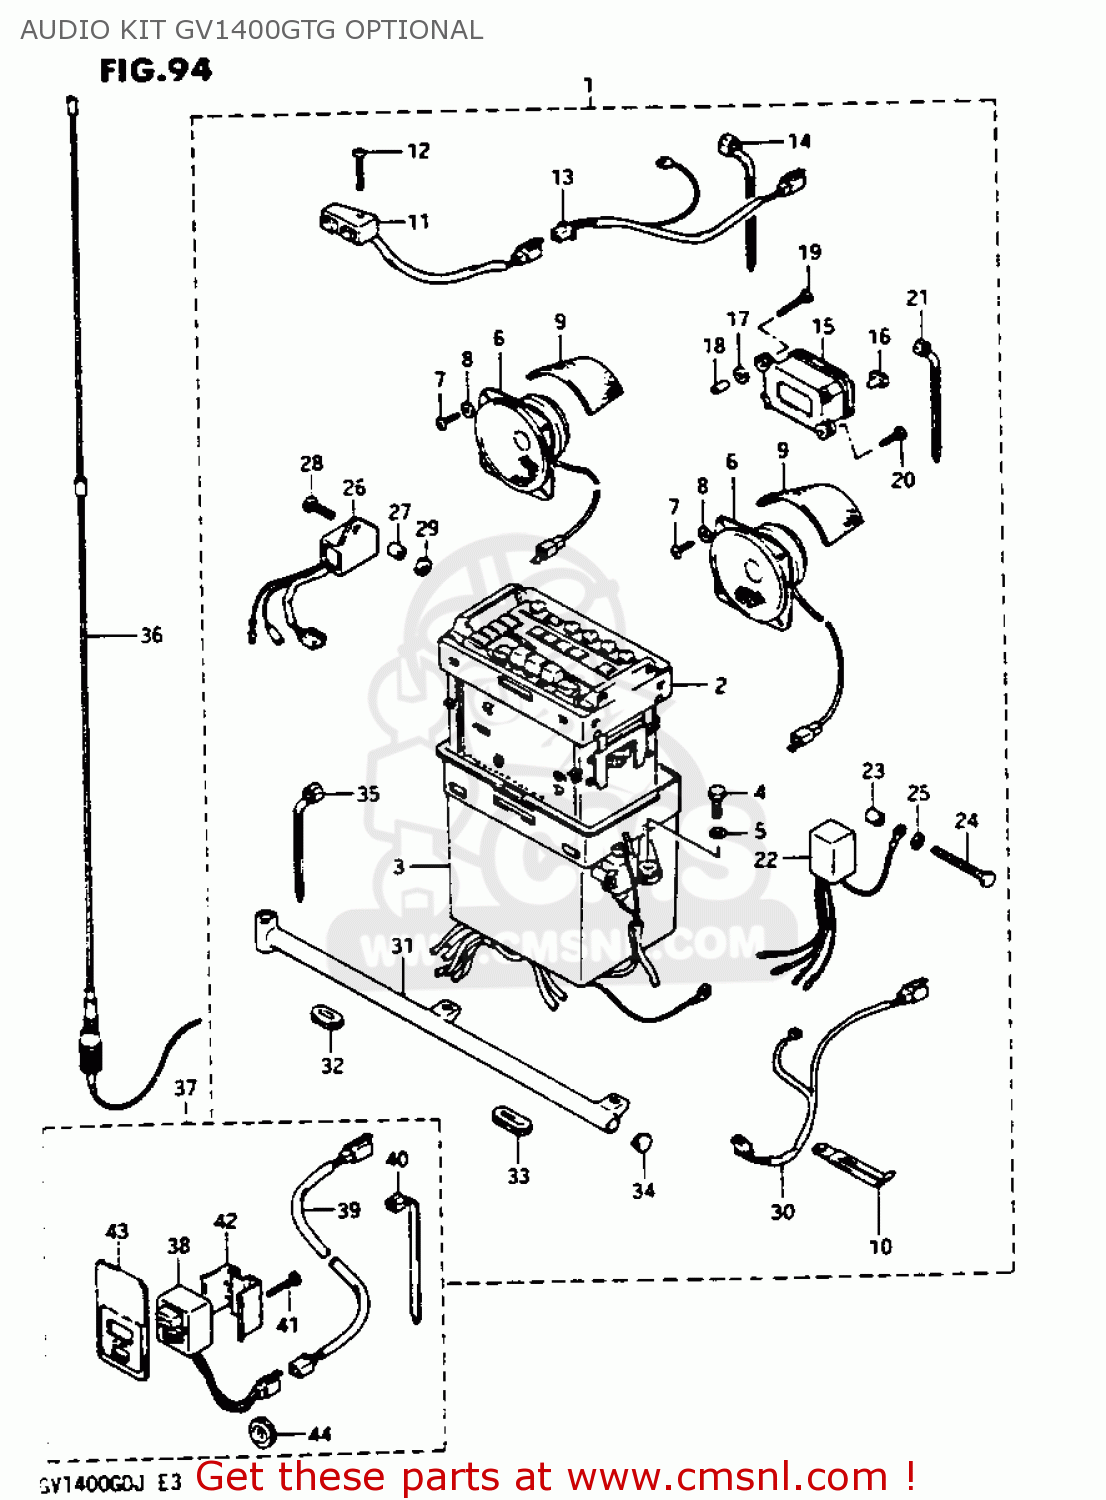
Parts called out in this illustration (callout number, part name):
1	AUDIO SET
2	TUNER ASSEMBLY
3	CASE ASSEMBLY,TUNER
4	BOLT,M6X1X20
5	WASHER,LOCK
6	SPEAKER
7	SCREW
8	WASHER
9	COVER,SPEAKER
10	CLAMP
11	SWITCH,RADIO CHANNEL SELECT
12	SCREW
13	WIRE,RADIO CHANNEL SELECTOR
14	CLAMP(L:165)
15	INDICATOR ASSEMBLY,TUNER C
16	BULB 14V
17	WASHER (4X16X1.2)
18	SPACER (5.2X8X12.5)
19	SCREW
20	SCREW
21	CLAMP(L:165)
22	CONDENSER ASSEMBLY,REGULATOR
23	SPACER (6.5X10.5X13.5)
24	BOLT ,6X35
25	WASHER
26	FILTER ASSEMBLY,FAN MOTOR
27	SPACER (6.8X10X10)
28	SCREW
30	WIRE,AUDIO POWER SOURCE
31	HOLDER,ANTENNA BAR
32	GROMMET
33	GROMMET
34	CAP(OD:20)
35	CLAMP(L:235)
36	ANTENNA ASSEMBLY,TUNER
37	CB CO-RIDER REMOTE CONTROL SWITCH
38	CONTROLLER ASSEMBLY,TUNER
39	WIRE,CHANNEL SELECT SWITCH
40	CLAMP(L:165)
41	SCREW
42	SWITCH
43	PANEL COMP,TUNER ASSEMBLY
44	GROMMET
